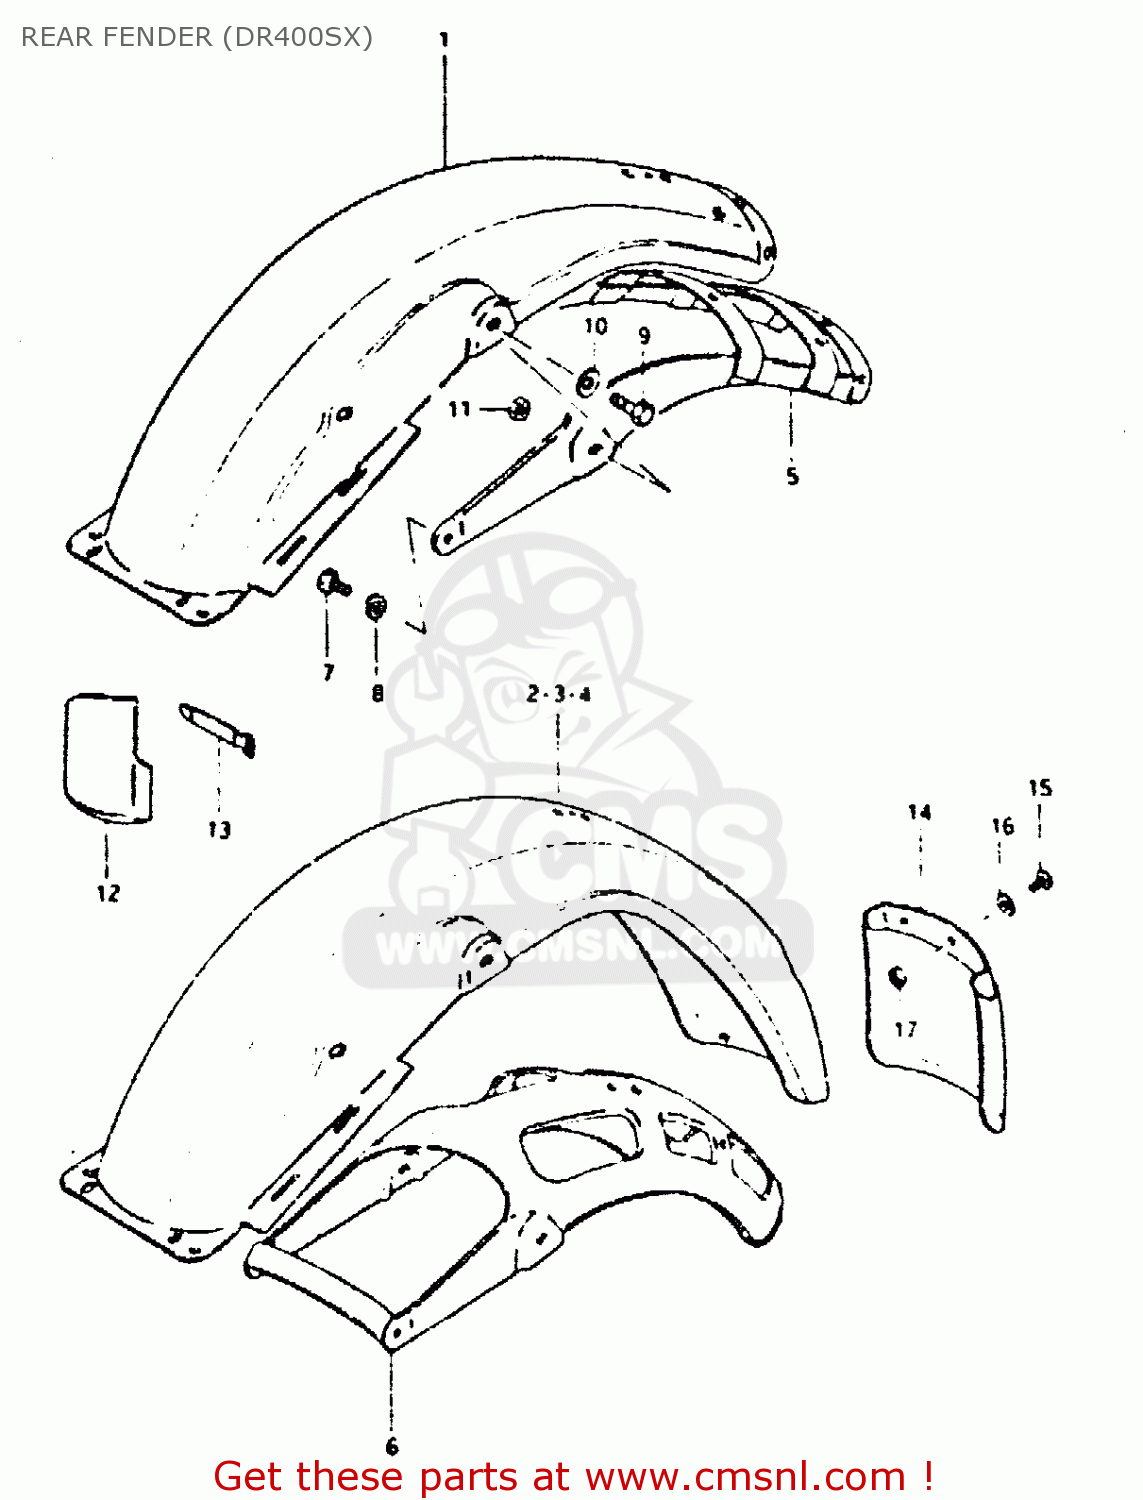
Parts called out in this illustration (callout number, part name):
1	FENDER, REAR
5	REINFORCEMENT,REAR FENDER
7	BOLT
8	LOCK WASHER
9	BOLT (8X30)
10	WASHER
11	NUT
12	MUD GUARD,REAR FENDER
13	CLAMP L:110
